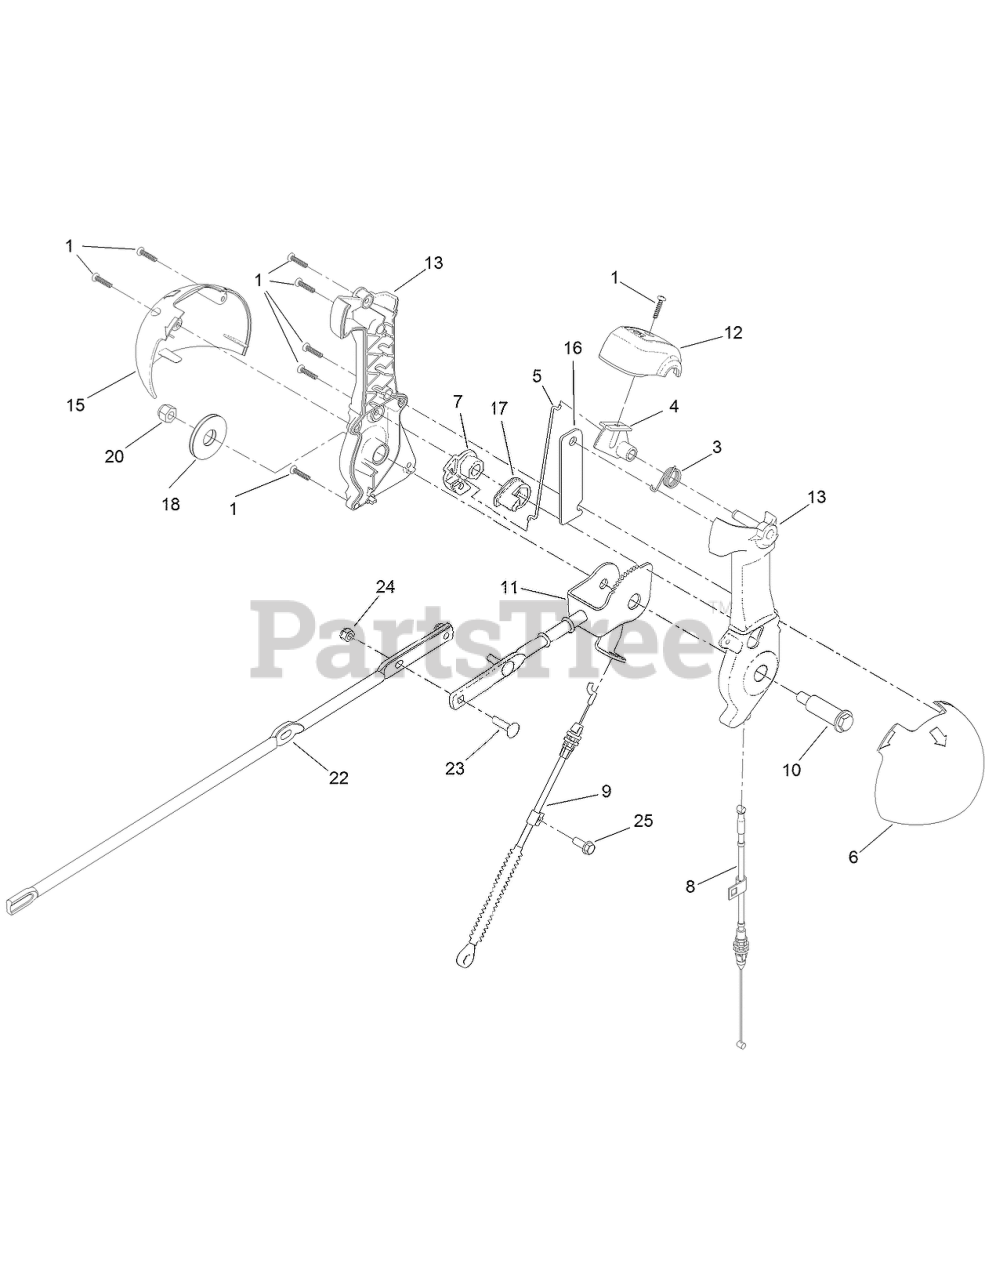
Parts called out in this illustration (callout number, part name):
1	SCREW-PPH
3	SPRING-TORSION
4	TRIGGER-LATCH
5	LINK-LATCH
6	GLOBE-QUICKSTICK, LH
7	LEVER-CABLE, DEFLECTOR
8	CABLE-RELEASE, CHUTE
9	CABLE-CONTROL, DEFLECTOR
10	SCREW-SHOULDER, HWH
11	ROD-CONTROL, CHUTE
12	CAP-LEVER
15	GLOBE-QUICKSTICK, RH
16	PLATE-STIFFNER
17	PAWL-LATCH
18	WASHER-FRICTION, COMPOSITE
20	NUT-HEX
22	ROD-CHUTE
23	BOLT-CARR
24	NUT-HEX
25	SCREW-HWH
